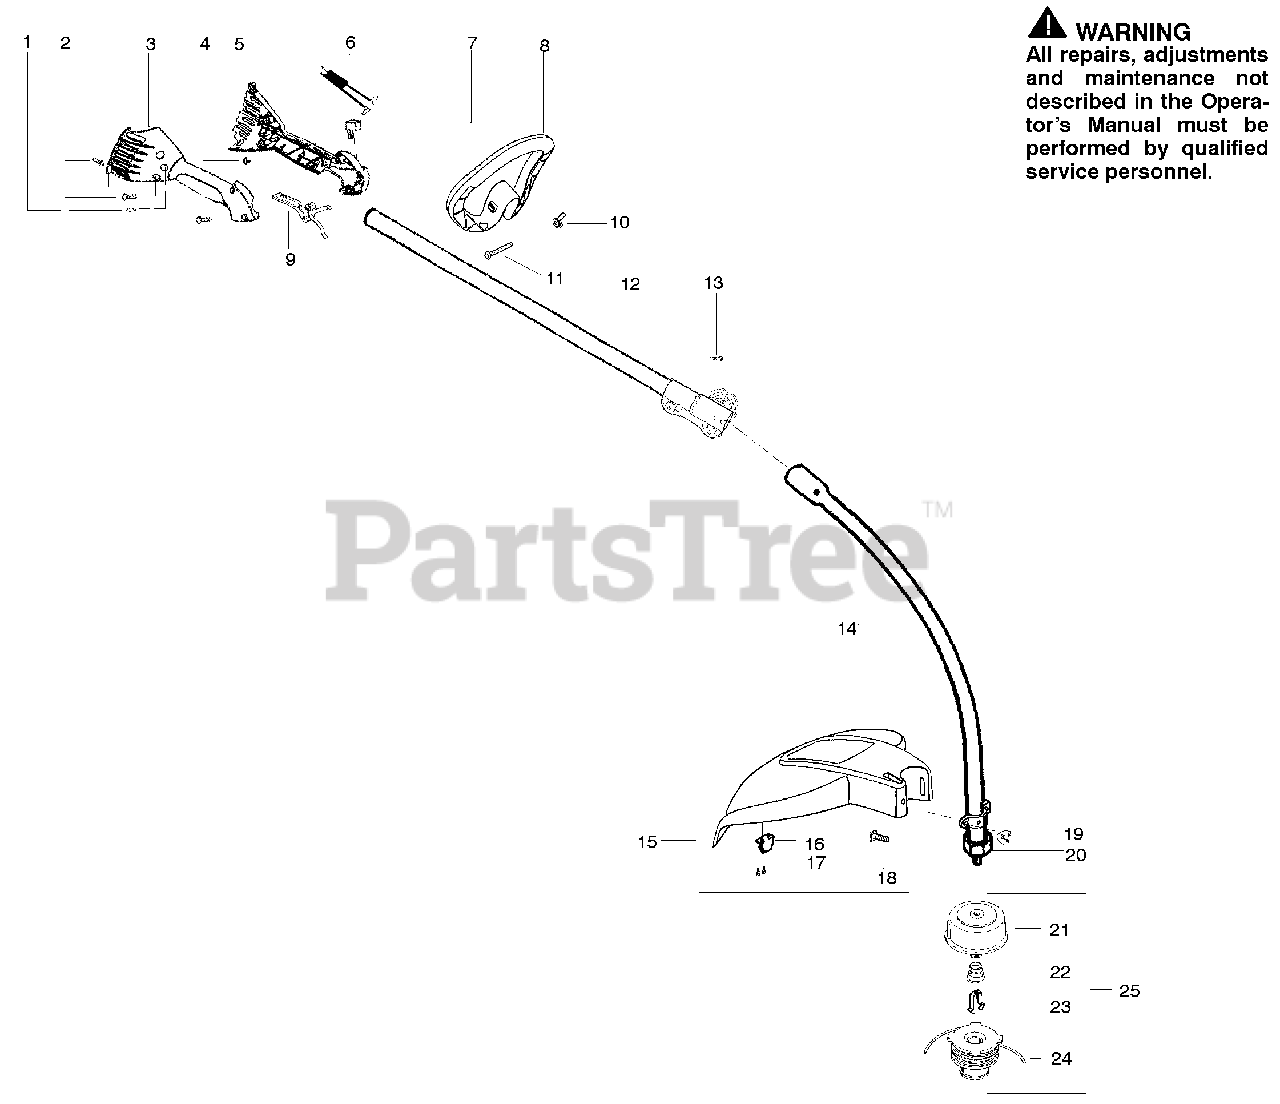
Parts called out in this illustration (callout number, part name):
1	Screw-alignment
3	Hsg.-Throttle right
4	Screw-Cable Retention
5	Hsg.-Left throttle
8	Handle-Assist
9	Trigger-Throttle
10	Wingnut
12	Assy-Upper Shaft
14	Assy-Lower Shaft
15	Kit-Shield Assy.
19	Wingnut
21	Assy-Hub/Arbor
22	Spring-Return
23	Retainer-Spool
24	Accy-Wound Spool
25	Accy-Cutting Head
